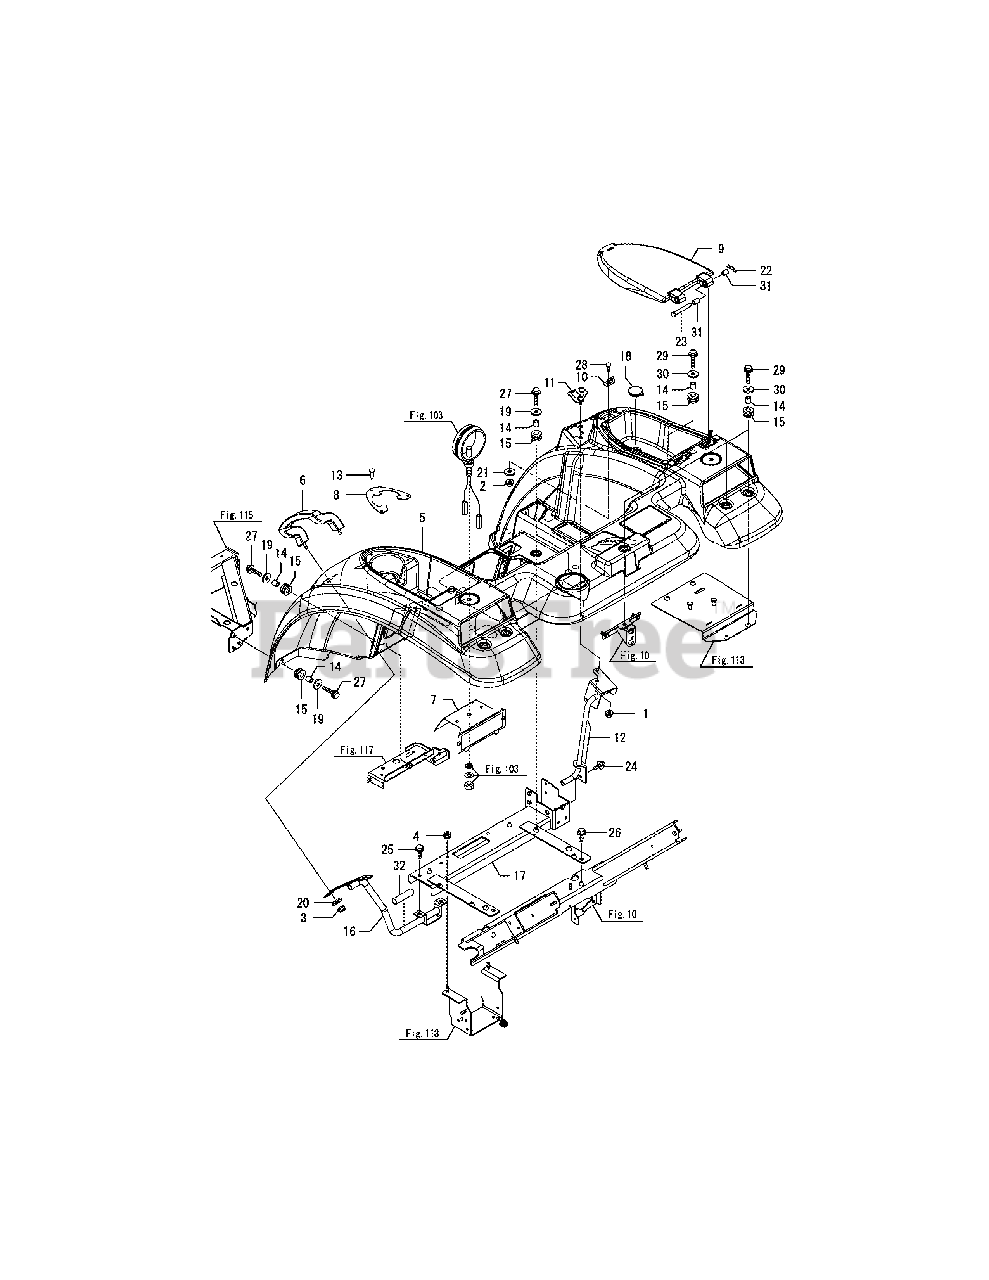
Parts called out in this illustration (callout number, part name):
1	NUT W/WASHER 8
2	NUT W/WASHER 8
3	NUT W/WASHER 8
4	NUT W/WASHER 8
5	FENDER M ASSY,
7	BRACKET ASSY, LAMP
8	COVER,CUP HOLDER
11	PLATE ASSY, PTO SW
12	STAY ASSY, PTO SW
14	COLLAR, CUSHION
16	STAY ASSY, GRIP
17	BRACKET ASSY, FENDER
22	SNAP PIN (JASO 8)
24	BOLT M 8X 20 PLATED
25	BOLT M 8X 20 PLATED
26	BOLT M 8X 20 PLATED
27	BOLT M 8X 35 PLATED
28	BOLT 8X20,SQ.ROOT
29	BOLT M8X35, COLLAR HD
30	WASHER 8,BC, PLAIN
